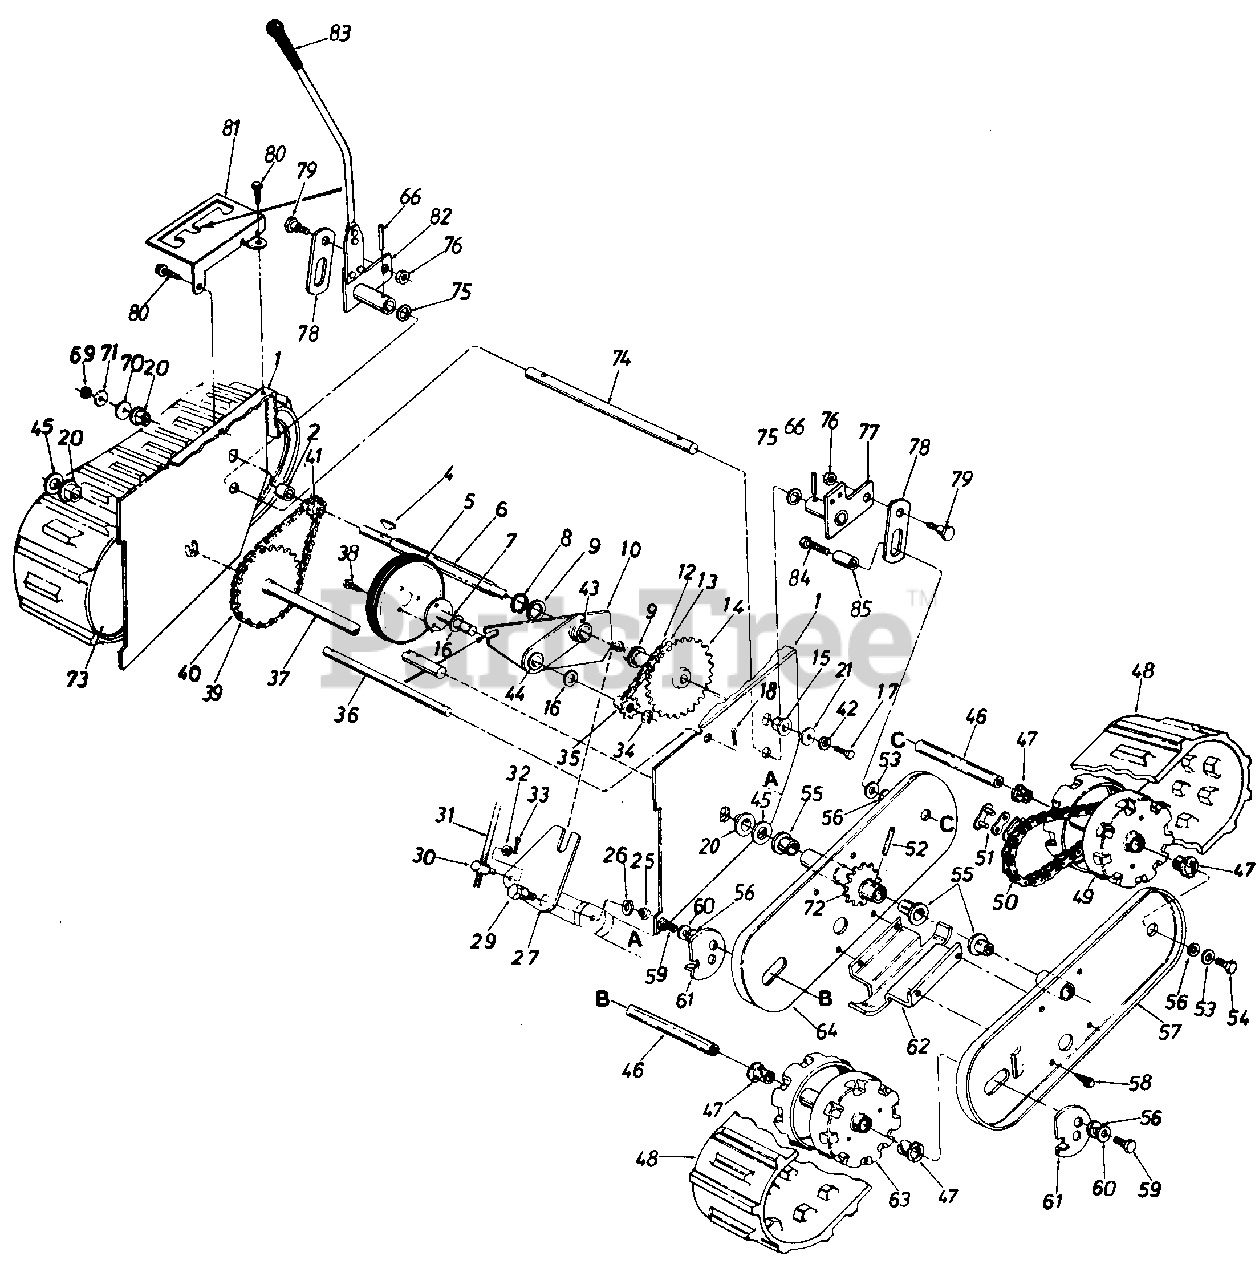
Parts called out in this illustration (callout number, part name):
1	Frame Ass'y.
2	Spacer .50" I.D. x .75" O.D. x.78" Lg.
4	#4 Hi-Pro Key 3/32 x 5/8" Dia.
5	Friction Wheel Ass'y.
6	Hex Shaft
7	Friction Wheel Mounting Plate 0 0 Ass'y.
8	Snap Ring 1.00" Dia. Shaft
9	Fl-Wash. 1.00" x 1.63 O.D. x .03
10	Sliding Bracket Ass'y.
12	#41 Chain 1/2" Pitch x 35 Links
13	Master Link for #41 Chain
14	32 Teeth Sprocket Ass'y.
15	Hex Flange Brg. .630" I.D.
16	Fl-Wash. .62" I.D. x 1.00" O.D. x .06
17	Hex Lock Bolt 5/16-18 x .62" Lg.
18	Cotter Pin 3/32" Dia. x .75" Lg.
20	Flange Brg. w/Flats .75" I.D.
21	Fl-Wash. .34" I.D. x 1.12" O.D. x .125
25	Hex Jam Nut 3/8-16 Thd.
26	L-Wash. 3/8" I.D.
27	Shifting Linkage Bracket
29	Shld. Bolt .625" Dia. x .170" Lg.
30	Adjustment Ferrule
31	Shifting Rod 5/16" Dia. x 32.50" Lg.
32	Fl-Wash. .34" I.D. x .64" O.D. x .06
33	Cotter Pin 3/32" Dia. x .75" Lg.
34	Snap Ring .562" Dia. Shaft
35	Sprocket 7 Teeth x .50" Pitch
36	Shaft .50" Dia. x 9.50" Lg.
37	32 Teeth Wheel Shaft Ass'y.
38	Hex Wash. Hd. Self-Tap Scr. 5/16-24 x .50" Lg.
39	#420 Chain 1/2" Pitch x 39 Link
40	Master Link for #420 Chain
41	8 Teeth Center Sprocket
42	L-Wash. 5/16" I.D.
43	Plastic Bearing
44	Bronze Bearing
45	Fl-Wash. .76" I.D. x 1.49 O.D.
46	Wheel Shaft 5/8 x 4.25" Lg.
47	Flange Brg. .632" I.D.
48	Snow Track 5" x 48"
49	Drive Wheel Ass'y.
50	Chain #420 x 50 Pitch x 37 Links
51	Master Link #420
52	Spring Pin Spir. 1/4" Dia. x 1.50" Lg.
53	Bell-Wash. .345" I.D. x .88" O.D.
54	Hex Bolt 5/16-24 x .62" Lg.
55	Flange Brg. .757" I.D.
56	Fl-Wash. .510" I.D. x 1.0" O.D.
57	Outer Plate Ass'y. L.H.
58	Hex Wash. S-Tap Scr. 1/4-20 x .50" Lg.
59	Hex Bolt 5/16-24 x .62" Lg.
60	Bell-Wash. .345" I.D. x .88" O.D.
61	Track Adjuster
62	Skid Shoe
66	Spring Pin 1/4" x 1.25" Lg.
69	Hex Ins. L-Nut 1/2-20 Thd.
70	Fl-Wash. .53 I.D. x 1.25 O.D. x .10
71	Bell-Wash. .50 I.D. x 1.0 O.D. x .075
72	17T Sprocket Hub Ass'y.
73	Inner Plate Ass'y. R.H.
74	Track Lock Axle
75	Fl-Wash. 5/8 I.D. x ln O.D.
76	Hex L-Nut 3/8-16 Thd.
77	Pivot Arm Ass'y. L.H.
78	Slotted Link
79	Shld. Bolt .625" Dia. x .217
80	Hex Wash. AB-Tap Scr. 5/16 x .75" Lg.
81	Position Selector Plate
82	Track Lock Handle Ass'y.
84	Hex Bolt 5/16-24 x 1.25" Lg. Grade 5
85	Spacer..325" I.D.
